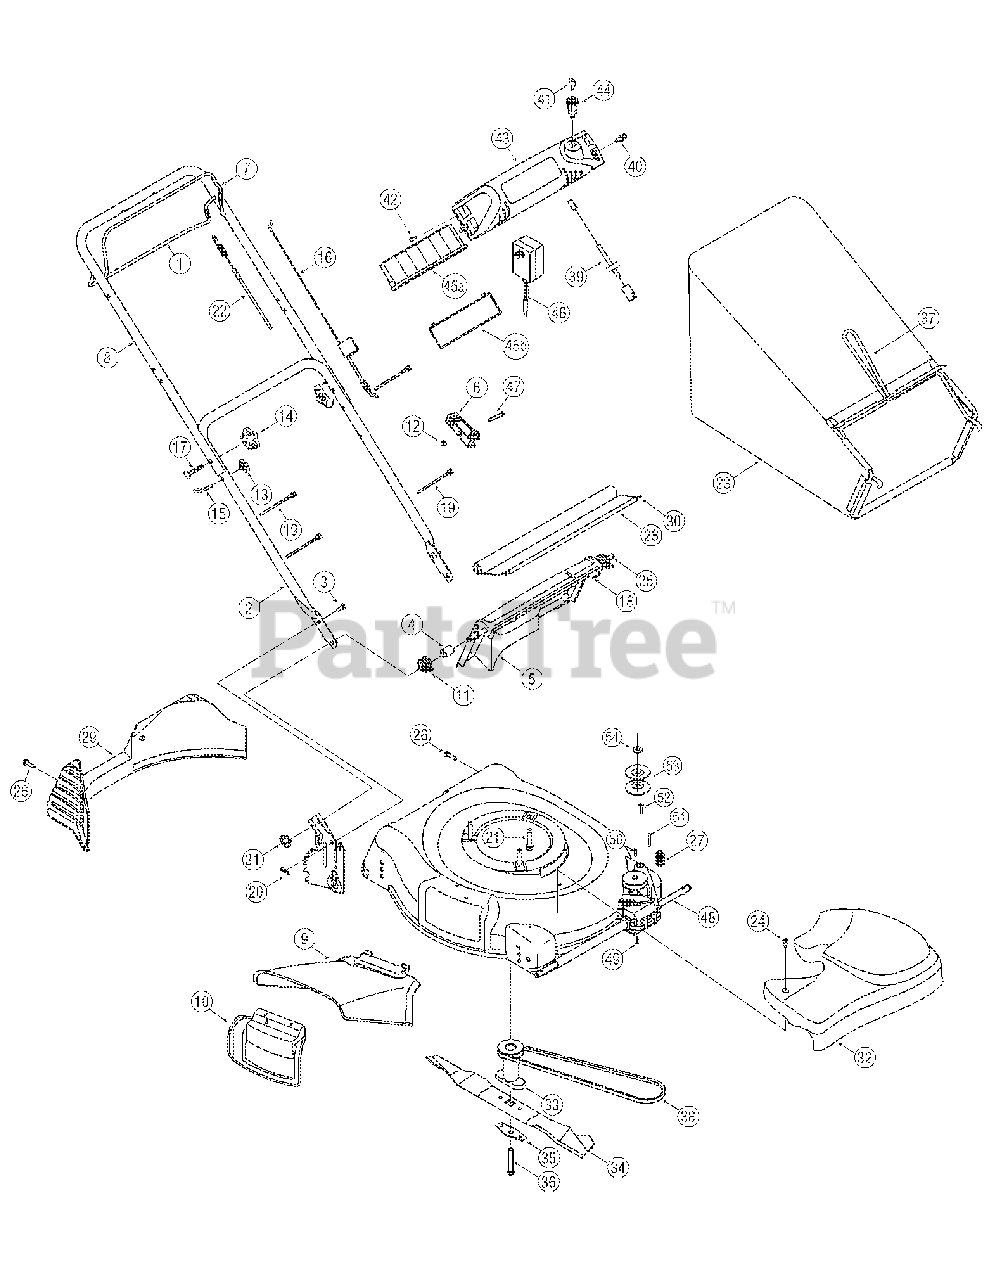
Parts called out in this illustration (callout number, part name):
1	Drive Control
3	Carriage Bolt 1/4-20
4	Spacer.375 x.50 x 1.02" Lg.
5	Rear Discharge Door
6	ERS Housing
9	Chute Deflector
10	Mulch Plug Complete
11	Torsion Spring - RH
12	Hex Lock Nut, 1/4-20
13	Handle Knob
14	Handle Knob
15	Eye Bolt
16	Control Cable - 39"
17	Carriage Bolt 5/16-18 x 2.0
18	Torsion Spring - LH
19	Cable Tie
20	Cotter Pin
21	Self-Tapping Sems Screw
22	Drive Cable - 48.75"
23	Grassbag Assembly
24	Shoulder Screw # 12 -24
25	Pivot Rod
26	Screw, 1/4-15 x 1.25
27	Belt Tension Spring
28	Rear Trailing Shield
29	Rear Baffle
30	Wire
31	Wing Nut
32	Transmission Cover
33	Blade Adapter
34	21" Mulching Blade
35	Blade Bell Support
36	Hex Screw 3/8-24 x 2.50
38	V-Belt
39	Electric Starter Harness
40	Rivet
41	Key
42	Screw, #10-16 x .75
43	Battery Hsg. (Used w/ Ref.# 45a)
43	Battery Hsg. (Used w/ Ref.# 45b)
44	Key Switch
46	Battery Charger
47	Screw, 1/4-20 x 1.75
48	Transmission Assembly
49	Torx Screw
50	Spirol Pin
51	Dowel pin
52	Screw, #12-16 x 1.00
53	Pulley, 3.82 x .313 x .68
54	Bell Washer, .325 x .930 x .45
